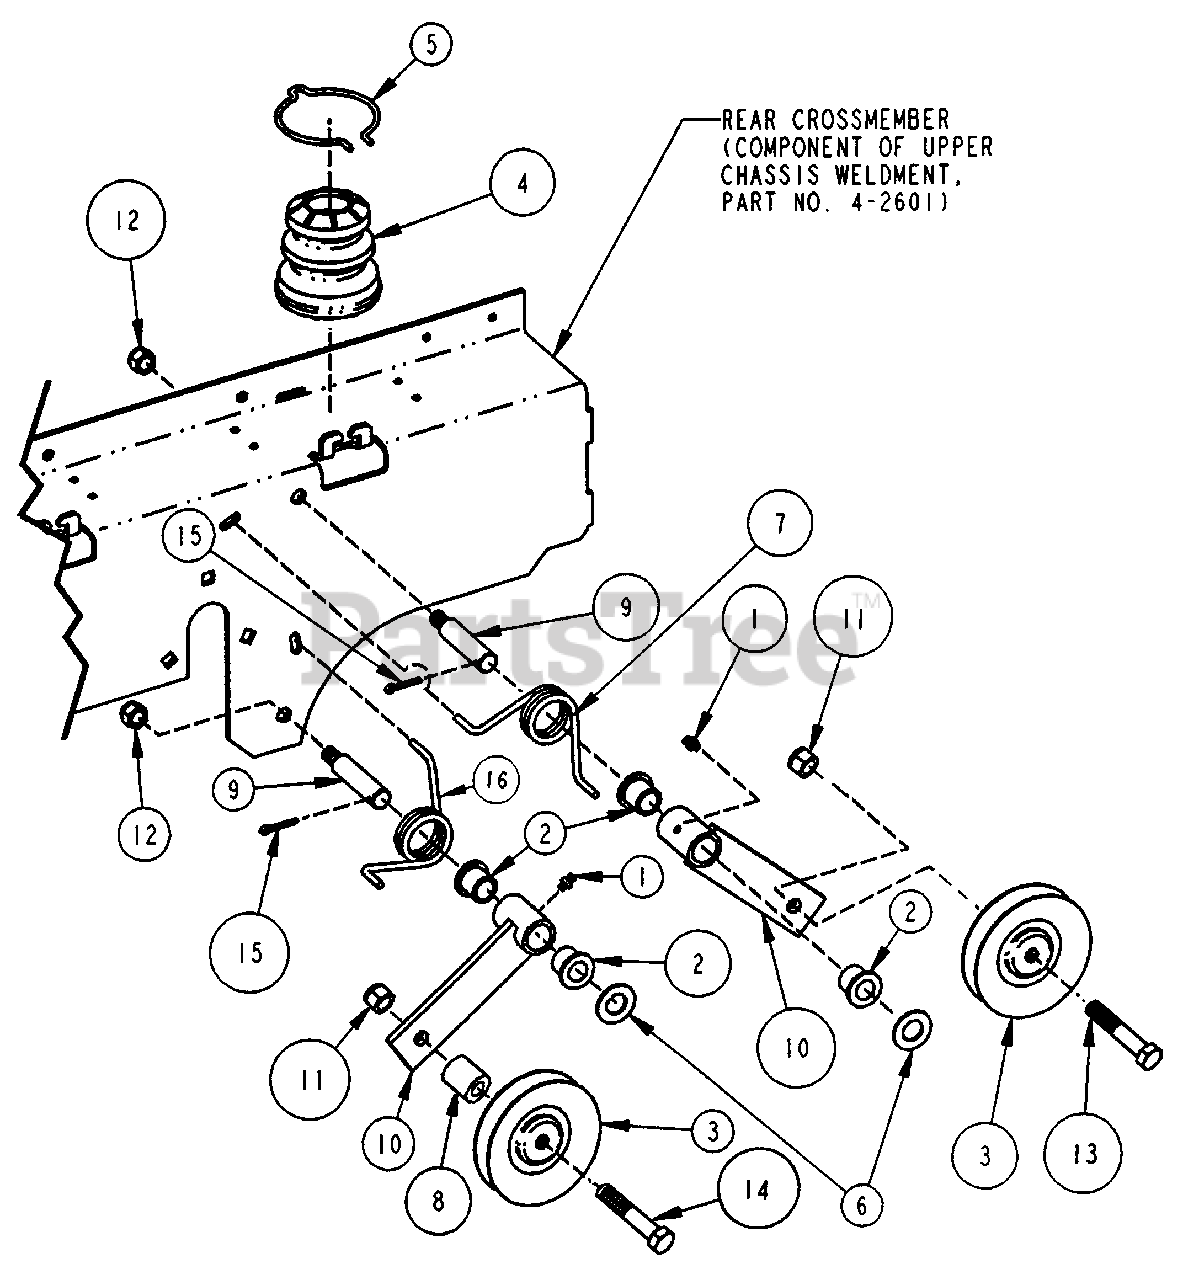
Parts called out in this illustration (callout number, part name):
1	LUBE FITTING, Straight (press-fit for .187 dia. Hole)
2	BUSHING, 9/16 I.D., 3/4" O.D.
3	PULLEY, Idler 3.48 O.D. A Section
4	COVER, Spring (Rubber)
5	CLIP, Seat Cushion
6	WASHER, 9/16 Flat (Type B)
7	SPRING, Torsion
8	SPACER, 3/8 I.D. 5/8 O.D. x 5/8" Long
9	PIN, 3/8-24
10	IDLER ARM (Weldment)
11	NUT, 3/8-16 HEX NYLON LOCK
12	NUT, 3/8-24 Hex Nyloc
13	SCREW, 3/8-16 x 1-3/4" Hex Head Cap, Grade 5
14	SCREW, 3/8-16 x 2-1/4" Hex Head Cap, Grade 5
15	COTTER PIN, 1/8 x 3/4"
16	SPRING, Torsion
